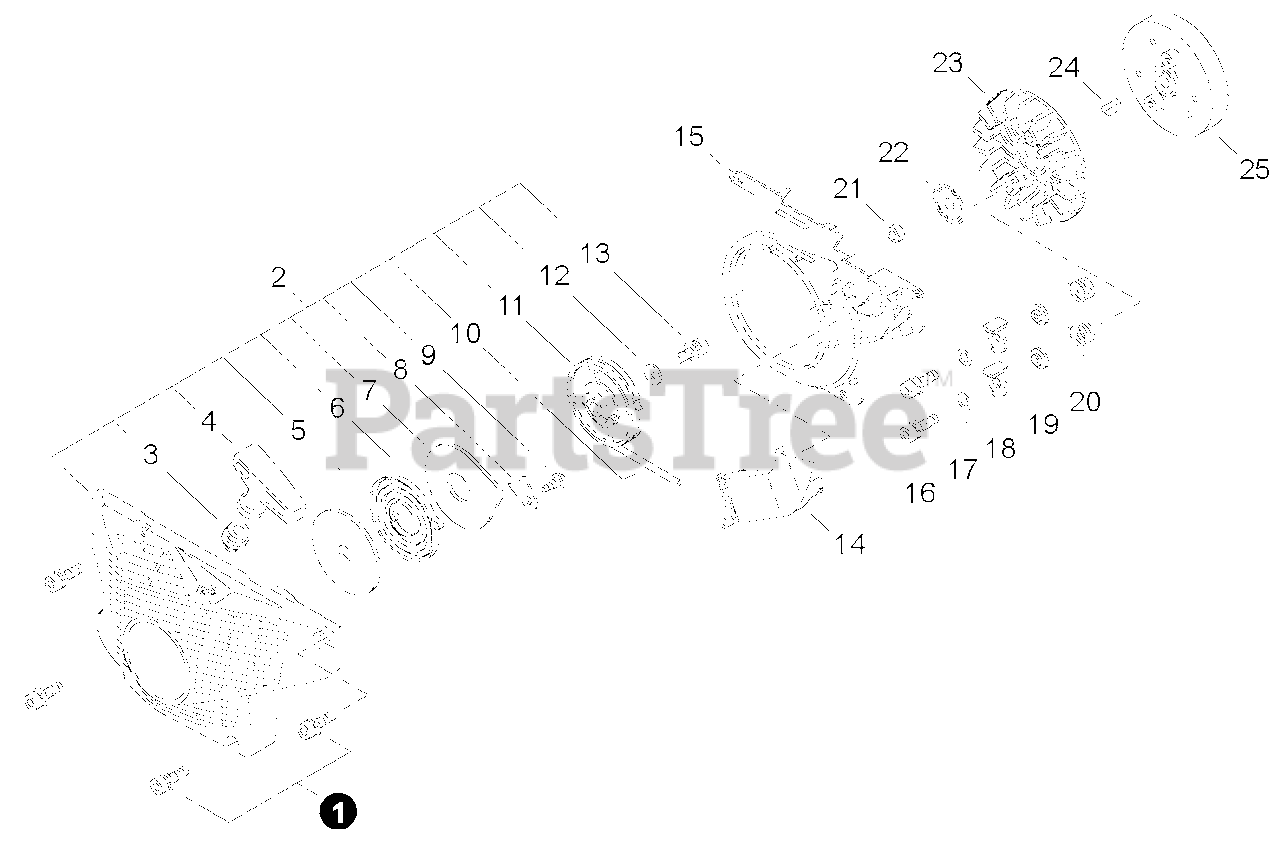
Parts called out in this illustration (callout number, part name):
1	SCREW - 5X20
2	STARTER ASSY
3	GUIDE, ROPE
4	GRIP, STARTER
5	PLATE, STARTER
6	SPRING, REWIND
7	PLATE, STARTER
8	RETAINER, BRAKE BAND
9	SCREW - 4X8
10	ROPE, STARTER - 4X950
11	REEL, ROPE
12	WASHER - 5
13	SCREW - 5X14
14	DUCT, AIR
15	COVER, FAN
16	SCREW - 5X20
17	WASHER - 5
18	PAWL, STARTER
19	SPACER, PAWL
20	SPRING, RETURN
22	WASHER - CUP
25	FLYWHEEL
